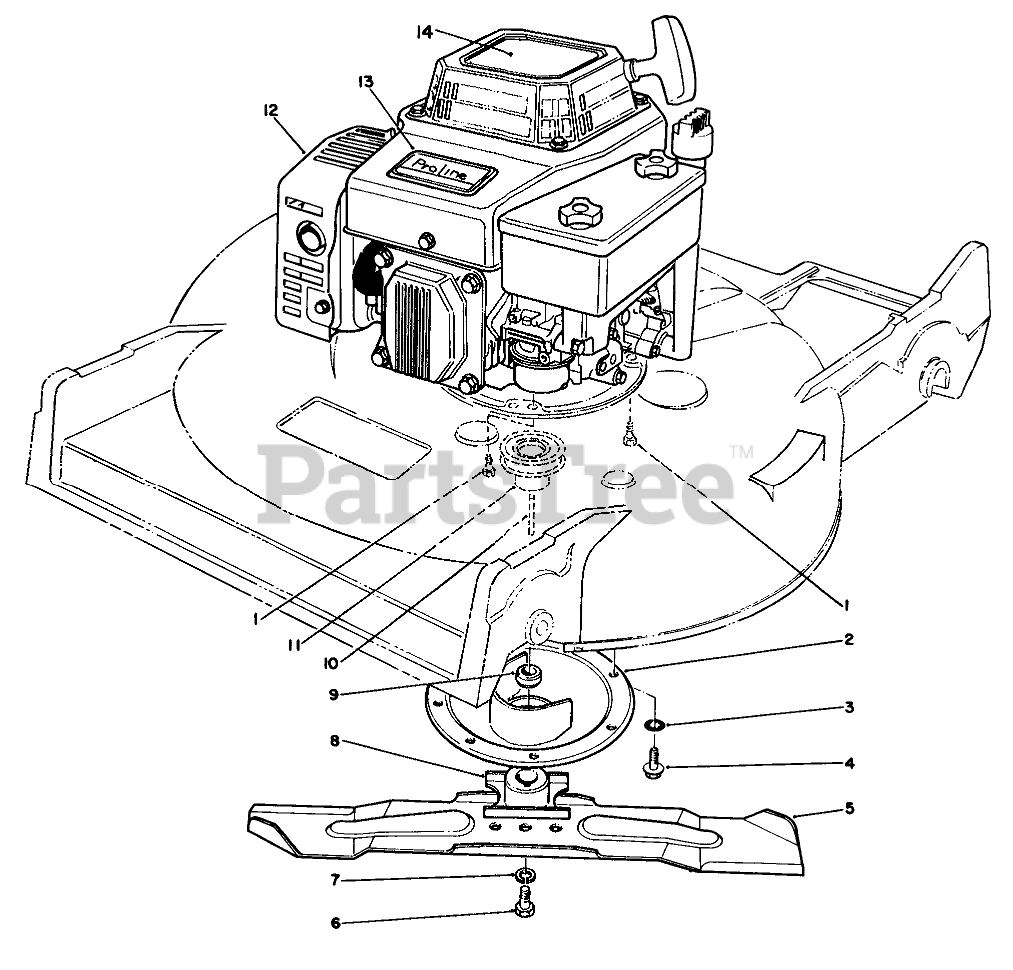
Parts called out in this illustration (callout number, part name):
1	SCREW-HWHTF
2	PROTECTOR-CRANKSHAFT
3	WASHER-LOCK, INTERNAL
4	SCREW-HWHTF
5	Key
6	SCREW-BLADE
7	WASHER-LOCK
8	RETAINER-BLADE
9	SPACER-BLADE RETAINER
10	KEY-SQUARE
11	PULLEY-DRIVER
12	Engine
13	DECAL - PROLINE
14	DECAL - RECOIL
